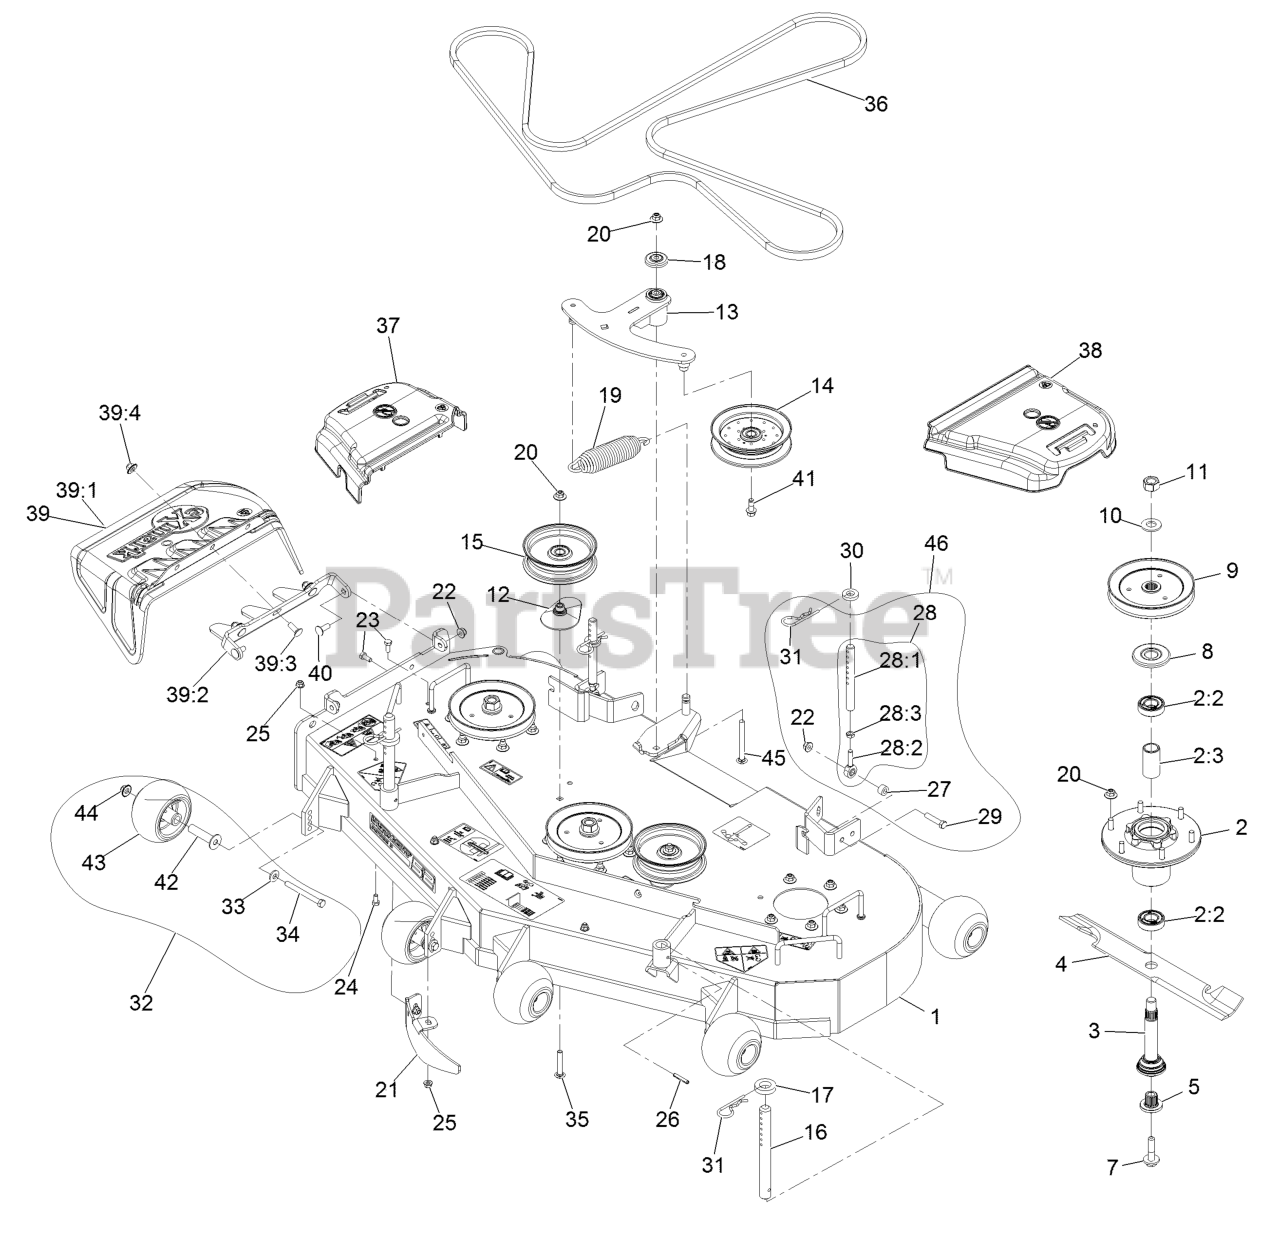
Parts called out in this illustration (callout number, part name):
1	ASM, Deck W/ Decals, 52"
2	ASM-Cutter Hsg With Bearings
2:2	Bearing-Ball
2:3	Spacer-Bearing
3	ASM-Spindle And Seal
4	Blade, Solid
4	Blade, Low Lift
4	Blade, Mulching
4	Blade-Notched
4	Blade-Extreme 2, 18.00"
5	Bushing, Splined
7	Screw-Sems 1/2-20 X 2.19
8	Guard,Bearing Top .989
9	Sheave,Blade Drive 6.50
10	Washer-Spring Disc 3/4
11	Nut-Hex
12	Spacer-Pulley
13	ASM, Deck Idler
14	Idler-Pulley, Flanged
15	Idler-Pulley, Flat
16	Rod, Deck Support
17	Spacer-Deck Support
18	Guard-Top
19	Spring-Extension
20	Nut-Nyloc 3/8-16 Flg
21	Baffle, Dogleg
22	Nut-Nyloc 3/8-16 Flg
23	Screw-HH 5/16-18 X 3/4
24	Screw-HH 5/16-18 X 5/8
25	Nut-Nyloc 5/16-18 Flg
26	Rollpin 1/4 X 1 1/2
28	Link Assy
28:1	Link, Rear Deck Support
28:2	Balljoint
28:3	Nut-Jam 3/8-24
29	Screw-HH 3/8-16 X 1 3/4
30	Spacer-Blade Drive
31	Hairpin-Cotter #206
32	Kit, Anti-Scalp Roller
33	Washer-Spring Disc 3/8
34	Screw-HH 3/8-16 X 3 3/4 GR 8
35	Bolt-Carriage 3/8-16 X 2 1/4
36	Belt, Deck
37	Cover-Belt, RH
38	Cover-Belt, LH
39	ASM, Discharge Chute
39:1	Chute, Discharge
39:2	Bracket, Discharge Chute
39:3	Bolt-Carriage 3/8-16 X 1
39:4	Nut-Nyloc 3/8-16 Flg
40	Bolt-Carriage 3/8-16 X 1
41	Screw-Hfh
42	Axle, Roller
43	Roller-Anti-Scalp
44	Nut-Nyloc 3/8-16 Flg
45	Bolt-Carriage 3/8-16 X 3 3/4
46	Kit, Support Link W/Pin
